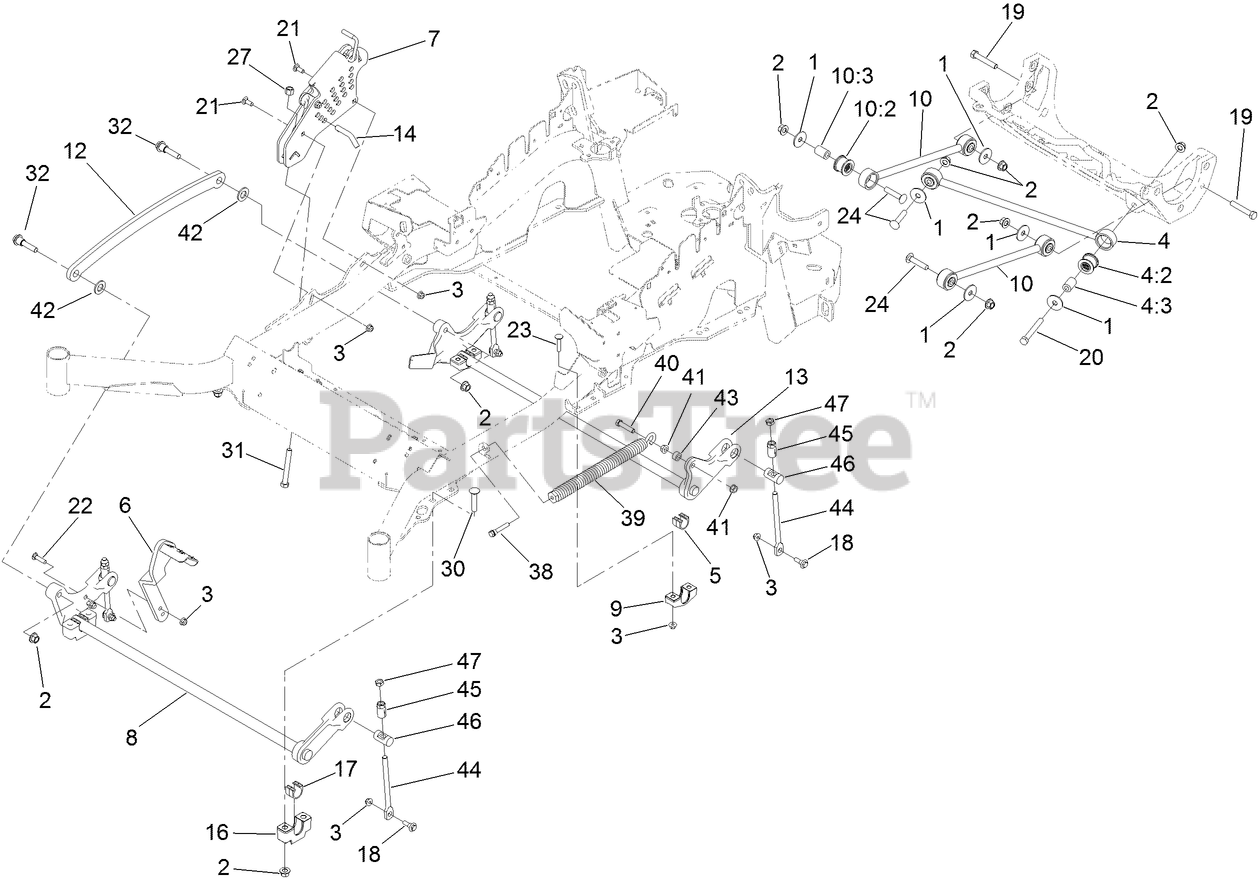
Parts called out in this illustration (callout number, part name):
1	WASHER-THRUST
2	NUT-LOCK
3	NUT-HF, NI
4	PANHARD ROD ASM
4:2	BUSHING-SUSPENSION, RUBBER
4:3	SPACER
5	BEARING-CROSS SHAFT, REAR
6	LEVER-FOOT
7	HOC ASM
8	DECK LIFT-FRONT
9	SUPPORT-CROSS SHAFT, REAR BEARING
10	DECK STRUT ASM
10:2	BUSHING-SUSPENSION, RUBBER
10:3	SPACER
12	LINK-LIFT, DECK
13	LIFT-DECK, REAR
14	PIN-HOC
16	SUPPORT-CROSS SHAFT, BEARING
17	BEARING-CROSS SHAFT, FRONT
18	SCREW-SHOULDER, HHF
19	SCREW-HH
20	SCREW-HH
21	BOLT-CARR
22	SCREW-CARR
23	SCREW-CARR
24	SCREW-CARR
27	NUT-LOCK, NI
30	BOLT-CARR
31	BOLT-TAP
32	SCREW-HHF, SHOULDER
38	BOLT-SHOULDER
39	SPRING-EXTENSION
40	SCREW-HH
41	NUT-HF
42	WASHER-FLAT
43	SPACER
44	LINK-ADJUSTER, DECK LIFT
45	ADJUSTER-LIFT, DECK
46	TRUNNION
47	NUT-JAM
